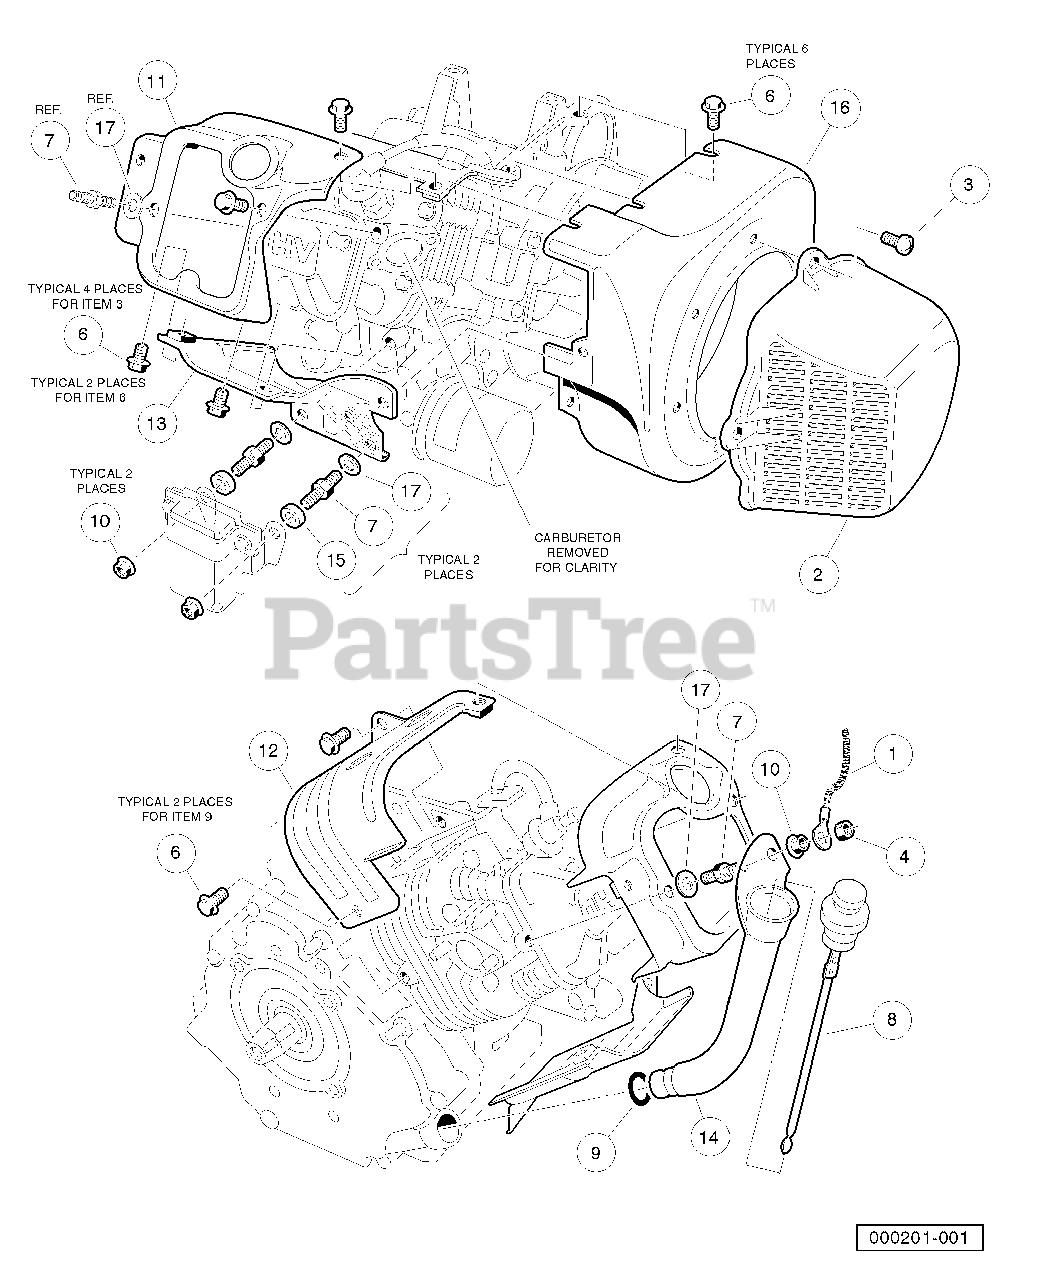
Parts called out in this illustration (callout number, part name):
1	Wire Assembly, #10, Uninsulated
2	Shroud, Fan
3	Screw, M6-1.00 X 10mm Pan Hd
4	Locknut, M6-1.00 Nylon Insert
5	Engine, FE350 (cw) without ACR
6	Bolt, Flange Head, M6 x 1 x 12 mm
7	Bolt, Two-Ended
11	Shroud, Engine
12	Shroud, Engine
13	Shroud, Engine
14	Tube, Oil Filler
15	Spacer 6.50 X 12 X 5.5
16	Housing, FE350 Fan
17	Washer, 6mm Flat
